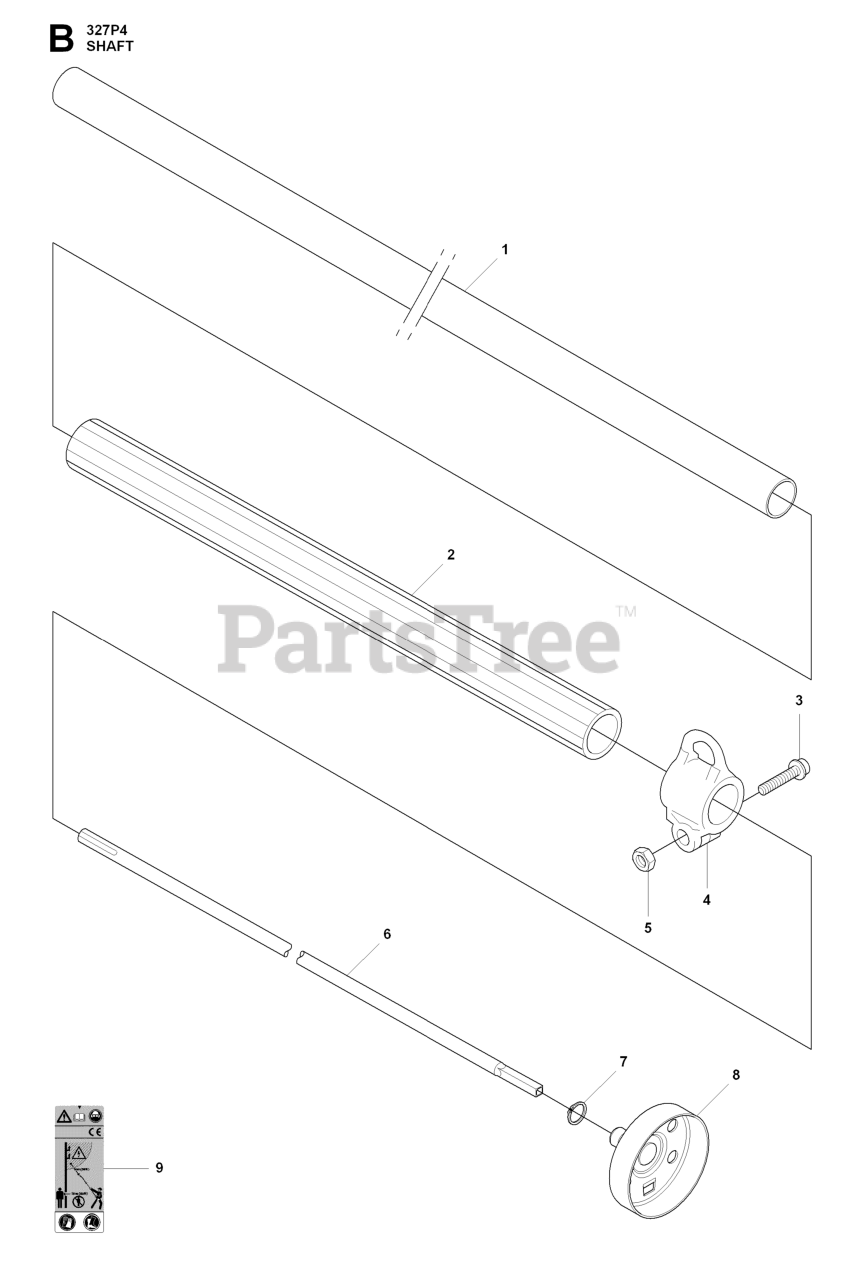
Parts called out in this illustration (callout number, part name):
1	TUBE
3	SCREW
4	HARNESS HOLDER
6	SHAFT P4
7	RETAINING RING SGA 10
8	CLUTCH DRUM
9	DECAL WARNING SPARK ARRESTOR
